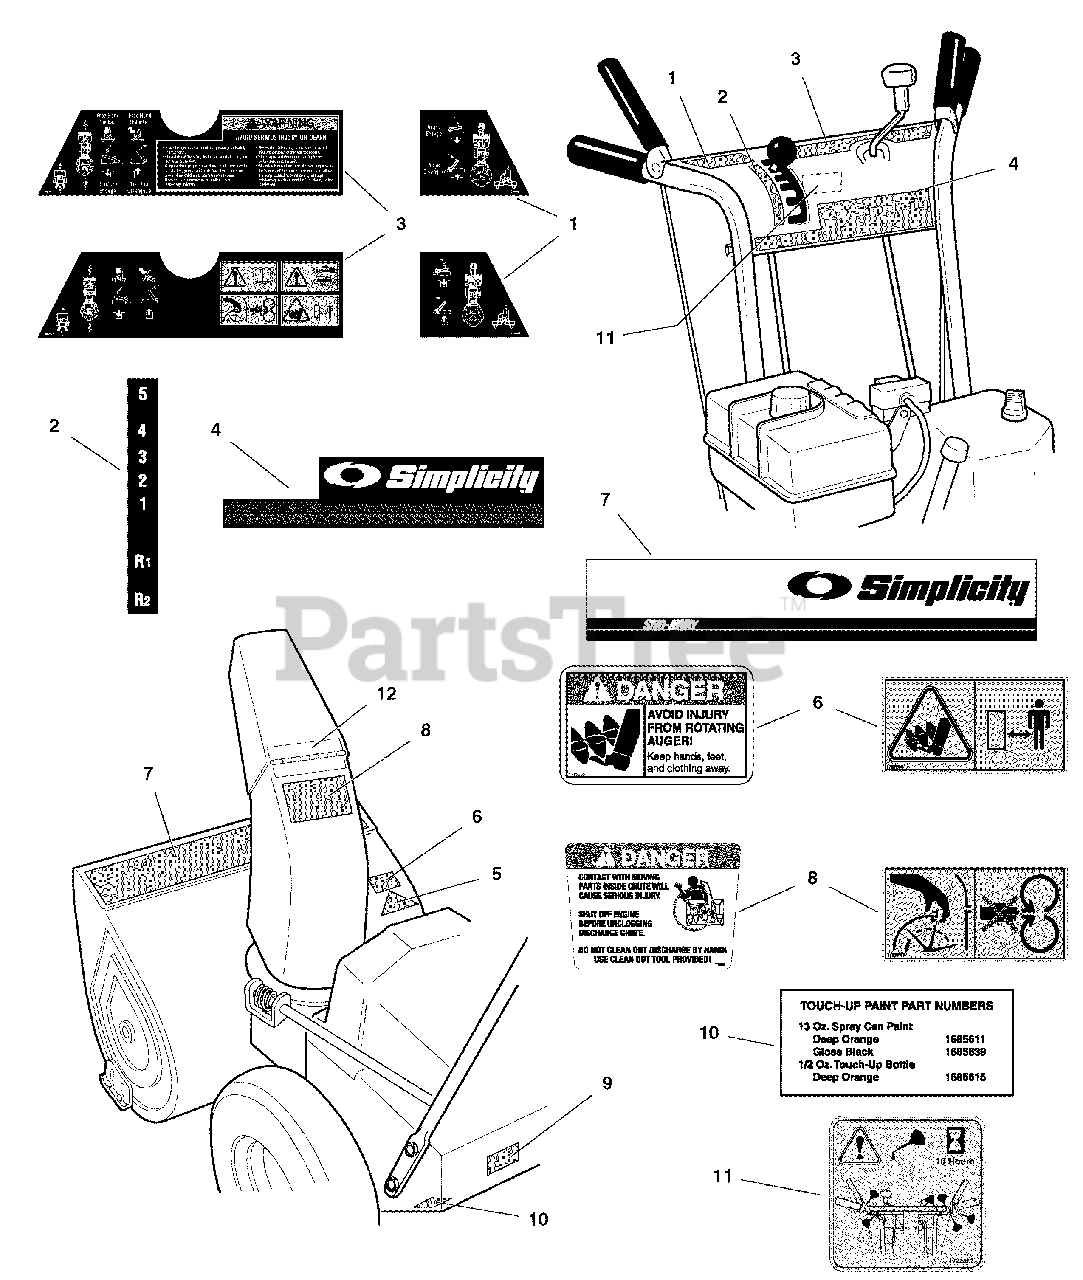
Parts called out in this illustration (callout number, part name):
1	DECAL, Dashboard, RH
1	DECAL, Dashboard, RH CE
2	DECAL, Shift Pattern
3	DECAL, Dashboard, LH
3	DECAL, Dashboard, LH CE
4	DECAL, Dash Front, Simplicity
5	DECAL, OPEI (Not Serviced)
6	DECAL, Danger, Auger
6	DECAL, Auger Warning, CE
7	DECAL, Stripe, Simplicity Intermediate 555
8	DECAL, Danger, Chute/Deflector
8	DECAL, Chute Warning, CE
9	I.D. Tag (Not Serviced)
10	DECAL, Paint
11	DECAL, Lube, Controls
12	DECAL, Hinge, Orange
